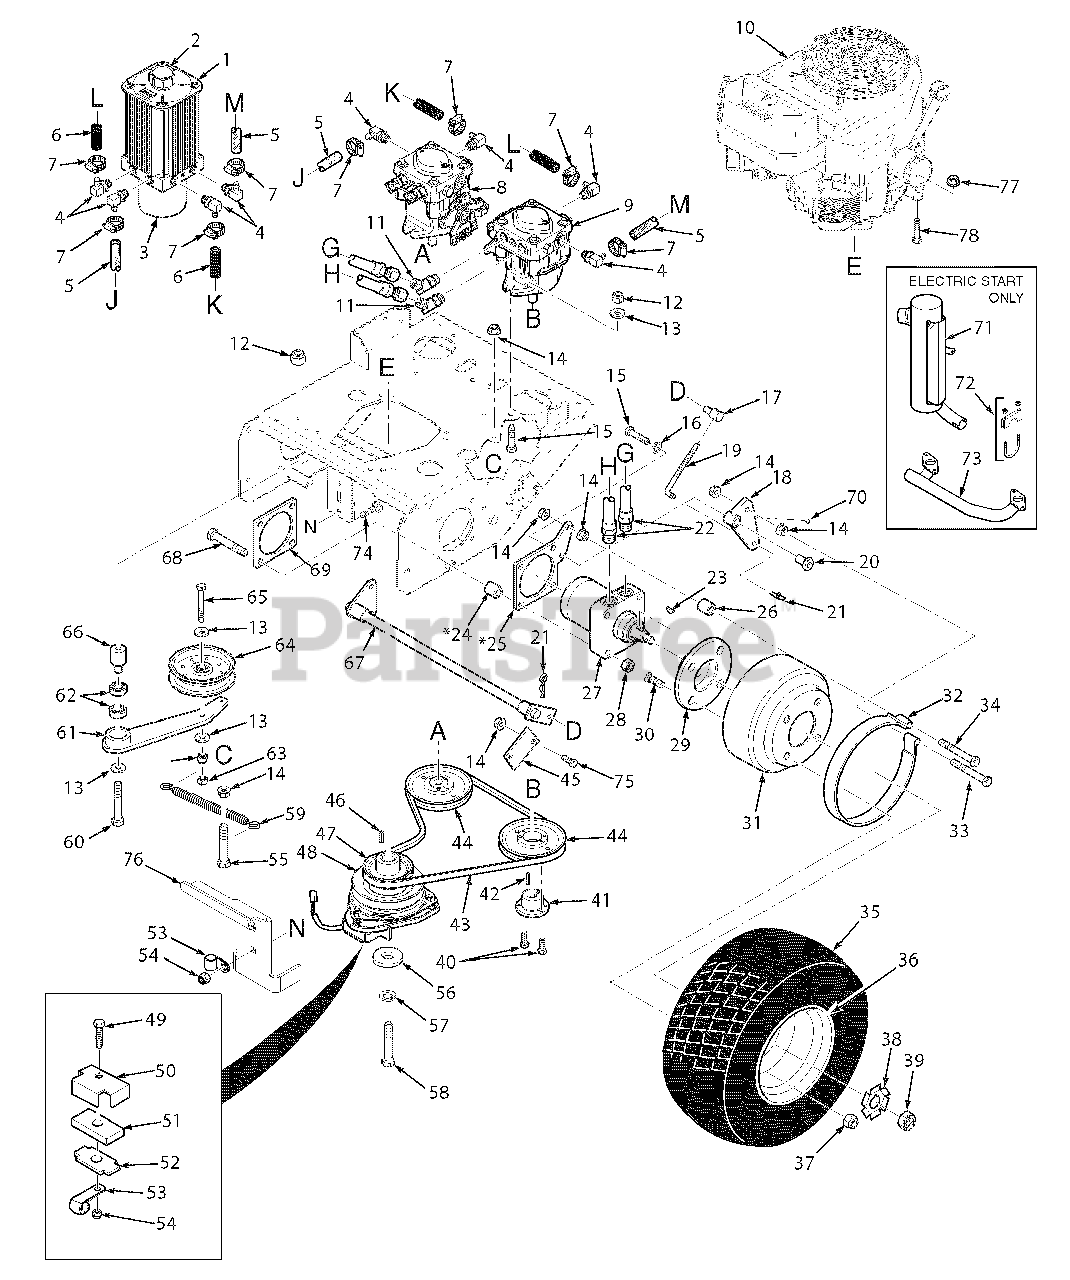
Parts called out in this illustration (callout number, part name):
1	Oil Reservoir Assembly
2	Cap, Oil Reservoir
3	Oil Filter
4	Elbow, 90Degree O-Ring 9/16-18 x 3/8" Hose
5	Hose, 3/8 Push Lock - Gray
6	Hose, 3/8 Push Lock -Black
7	Clamp, Hose .69" Max. Dia.
8	Pump, RH SWZV
9	Pump, LH SWZV
10	Engine, 19hp Kawasaki FH580V
11	Elbow, 45 Degree
12	Nut, Elastic Stop 3/8-16
13	Flatwasher, 3/8-.391 x .938 x .105 HD
14	N ut, Serrated Flange 3/8-16
15	Bolt, Hex Head 3/8-16 x 1-1/2"
16	Lockwasher, 3/8"
17	Swivel Joint
18	Brake Actuator Weldment, LH
19	Rod, Brake Lower
20	B ushing, Brake
21	Hair Pin Cotter, .094 x 1.62"
22	Hose Assembly
23	Key, 3/16 x 3/4" Woodruff
24	Spacer
25	Brake Plate
26	Spacer
27	Wheel Motor
28	Nut, Center Lock 1/2-13
29	Wheel Hub Assembly
30	Bolt, Serrated 1/2-20
31	Brake Drum
32	Brake Band Assembly
33	Bolt, Hex Head 3/8-16 x 2-1/4’
34	Bolt, Hex Head 3/8-16 x 3-1/4"
35	Wheel Assembly, 18 x 8.5-8
36	Rim w/Valve Stem
36	Tire, 18 x 8.5-8
37	L ug Nut
38	Lockwasher, Wheel Motor
39	Hex Castle Nut, 3/4-28 UNEF
40	Bolt, Hex Head 1/4-20 x 1" Grade 8
41	Tapered Hub
42	Key, 5.0 x 5.0 x 25mm
43	Belt, Pump Drive
44	Pulley, 5.45 O.D. Tapered Bore
45	Plate, Brake Keeper
46	Key, 1/4 x 1/4 x 3-3/4"
47	Pulley, 4.0 O.D. - 1" Bore
48	Clutch Assembly
49	Bolt, Hex Head 5/16-18 x 1-3/4"
50	R e t a i n e r , C l utch Pad
51	Rubber Pad
52	Plate, Backing
53	Clamp, Cable
54	Nut, Elastic Stop 5/16-18
55	Bolt, Hex Head 3/8-16 x 3-3/4" Grade 8
56	Flatwasher, 7/16-.469 x 1.75 x .25
57	Lockwasher, 7/16" Spring
58	Bolt, Hex Head 7/16-20 x 2-3/4" w/Patch
59	Spring, Transmission Idler
60	Bolt, Hex Head 3/8-16 x 3-1/4"
61	Idler Arm Assembly
62	Bearing
63	Nut, Center Lock 3/8-16
64	Pulley, 4-1/2" Idler
65	Bolt, Hex Head 3/8-16 x 2-3/4"
66	Pivot, Idler
67	Brake Bellcrank Weldment
68	Bolt, Hex Head 1/2-13 x 3-3/4"
69	Plate, Wheel Motor
70	Grease Fitting
71	Muffler
72	Clamp
73	Exhuast Manifold
74	Bolt, Carriage 5/16-18 x 1"
75	Bolt, Serrated Flange 3/8-16 x 3/4"
76	Plate, Clutch Bracket
77	Nut, Serrated Flange 5/16-18
78	Bolt, Hex Head 5/16-18 x 1-1/2"
